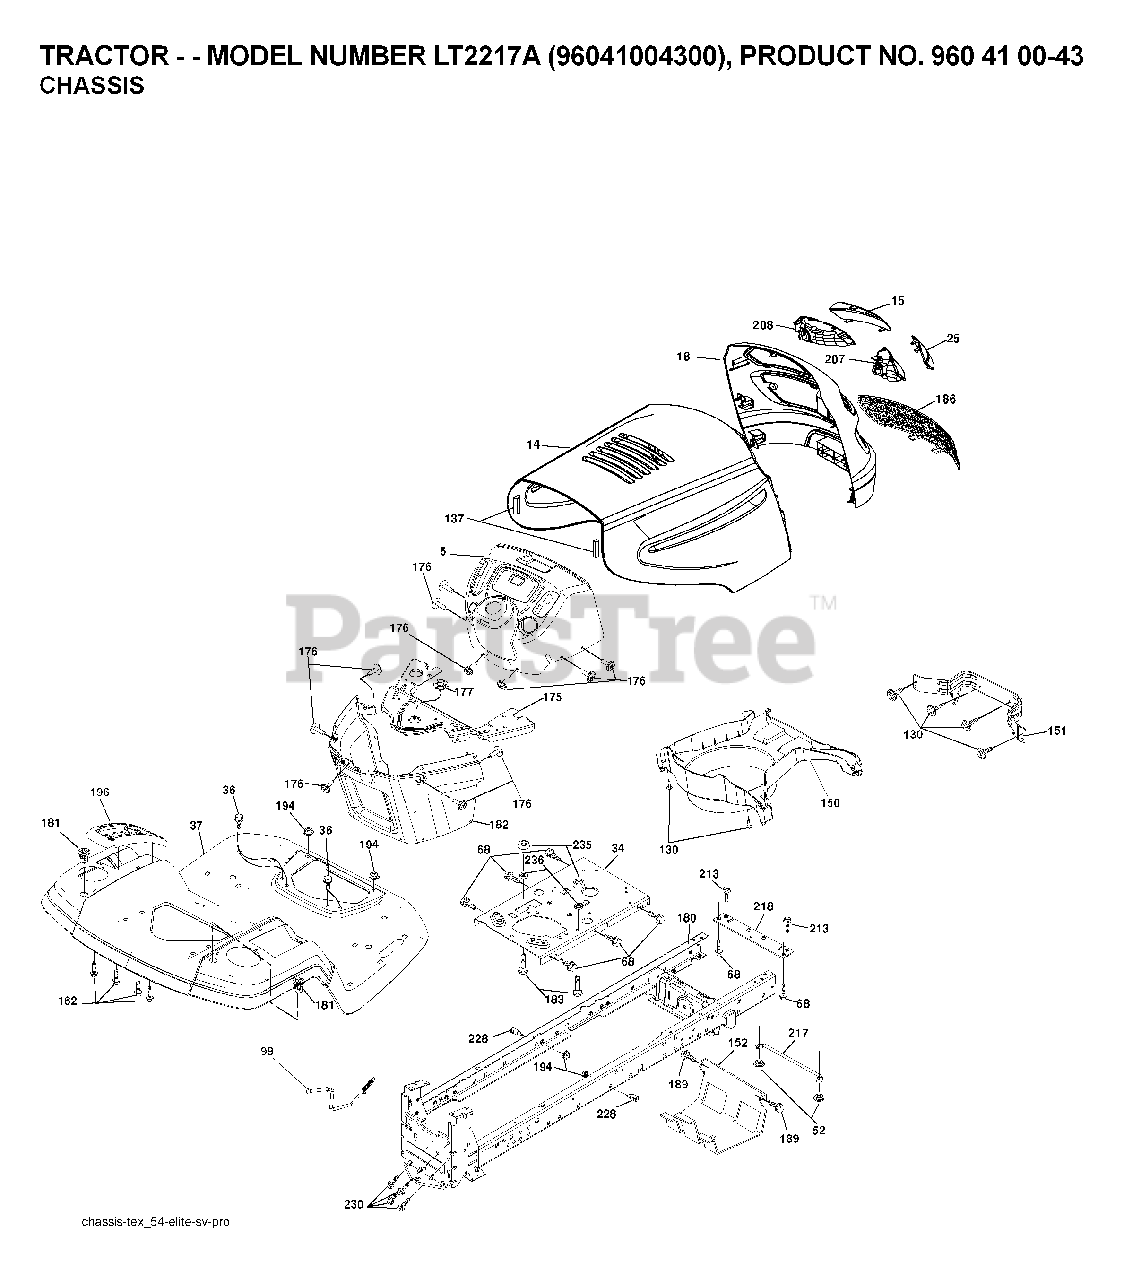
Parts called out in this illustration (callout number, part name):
34	PLATE.ENGINE.WELDED.CHASSIS
36	SCREW 5/16"
52	LOCKNUT
99	ROD ASM BYPASS
130	SCREW
137	BUMPER.HOOD.LARGE.1.75"
151	BRACKET PIVOT
152	SHIELD BROWNING
162	SCREW.1/4-20X5/8
175	CROSSMEMBER.LT
176	SCREW.#10-24X5/8.RN.QU
177	BUSHING STEERING
180	CHASSIS
181	FEND/FTRST.PCH.CPH.NFW
182	DASH.LOWER.LT.CCS
183	BOLT.5/16-18X1-1/4 FULL.THREAD
189	SCREW
194	NUT LOCK HEX FLANGE 5/16-18
196	CONSOLE.ASM.DECK.LIFT.TLT.BLAC
207	BEZEL GRILL RH
208	BEZEL GRILL LH
213	BOLT
217	ROD PIVOT CHASSIS/HOOD
218	X-PIECE.HOOD.STOP.NON/
228	STUD.FASTNER.W/ANTI-ROTATE
230	SHOULDER BOLT 5/16-18TT
235	SPACER FENDER
236	NUT.CENTERLOCK.5/16-
